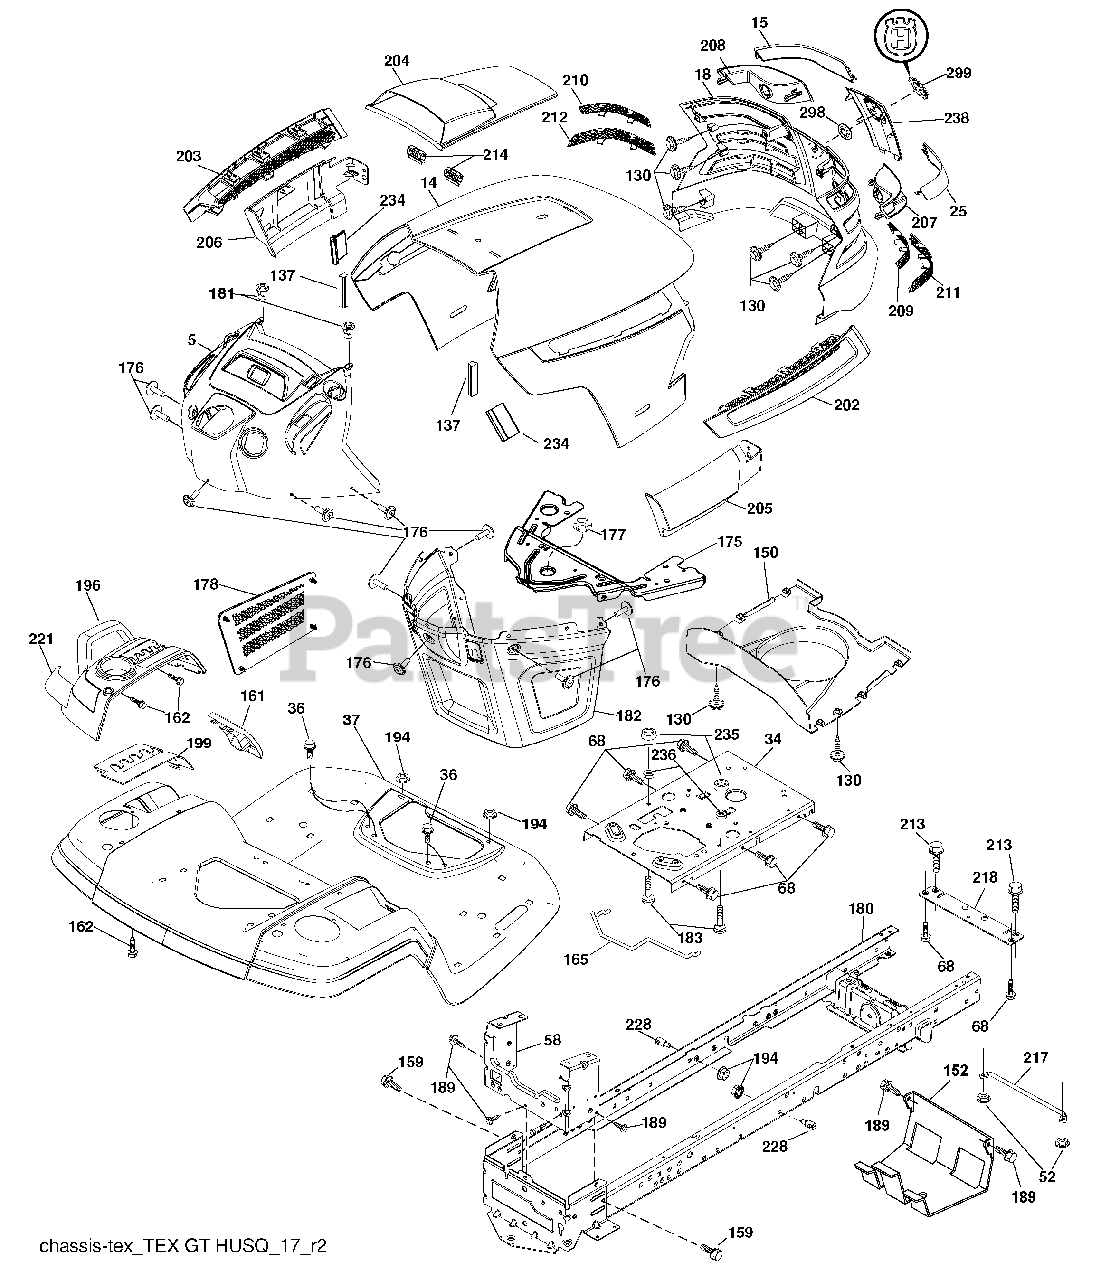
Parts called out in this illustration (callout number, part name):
14	Hood
18	Grille Asm.
34	Plate Engine
36	Screw 5/16-18 x 3/4
37	Fender
52	Nut Lock 5/16-18
58	Drawbar Upper
68	Screw 5/16-18 x 1/2
130	Screw #10 x 0.750
137	Bumper Dash
152	Shield Browning
159	Screw 3/8-16 x 3/4
161	Window Fuel
165	Support Tank Rear
175	Crossmember
176	Screw 10-24 x 5/8
177	Bushing Steering
178	Cargo Net Asm.
181	Bushing Mtg. Fender Crgo
182	Dash Lower
183	Bolt 5/16-18 x 1-1/4
189	Screw 5/16-18 x 3/4
194	Nut Lock Hex Flange 5/16-18
196	Console Asm. Deck Lift
199	Plate Deck Lift
202	Vent Side Hood RH
203	Vent Side Hood LH
204	Vent Top Hood
205	Skirt Hood Side RH
206	Skirt Hood Side LH
209	Insert Hex Top RH
210	Insert Hex Top LH
211	Insert Hex Bottom RH
212	Insert Hex Bottom LH
213	Bolt 5/16-18 unc x 3/4
214	Clip Retainer Tinner
218	X-Piece Hood Stop
221	Reflector LH
228	Stud Fastner
234	Bumper Hood
235	Spacer Fender
236	Nut Lock 5/16-18 unc
299	Logo
